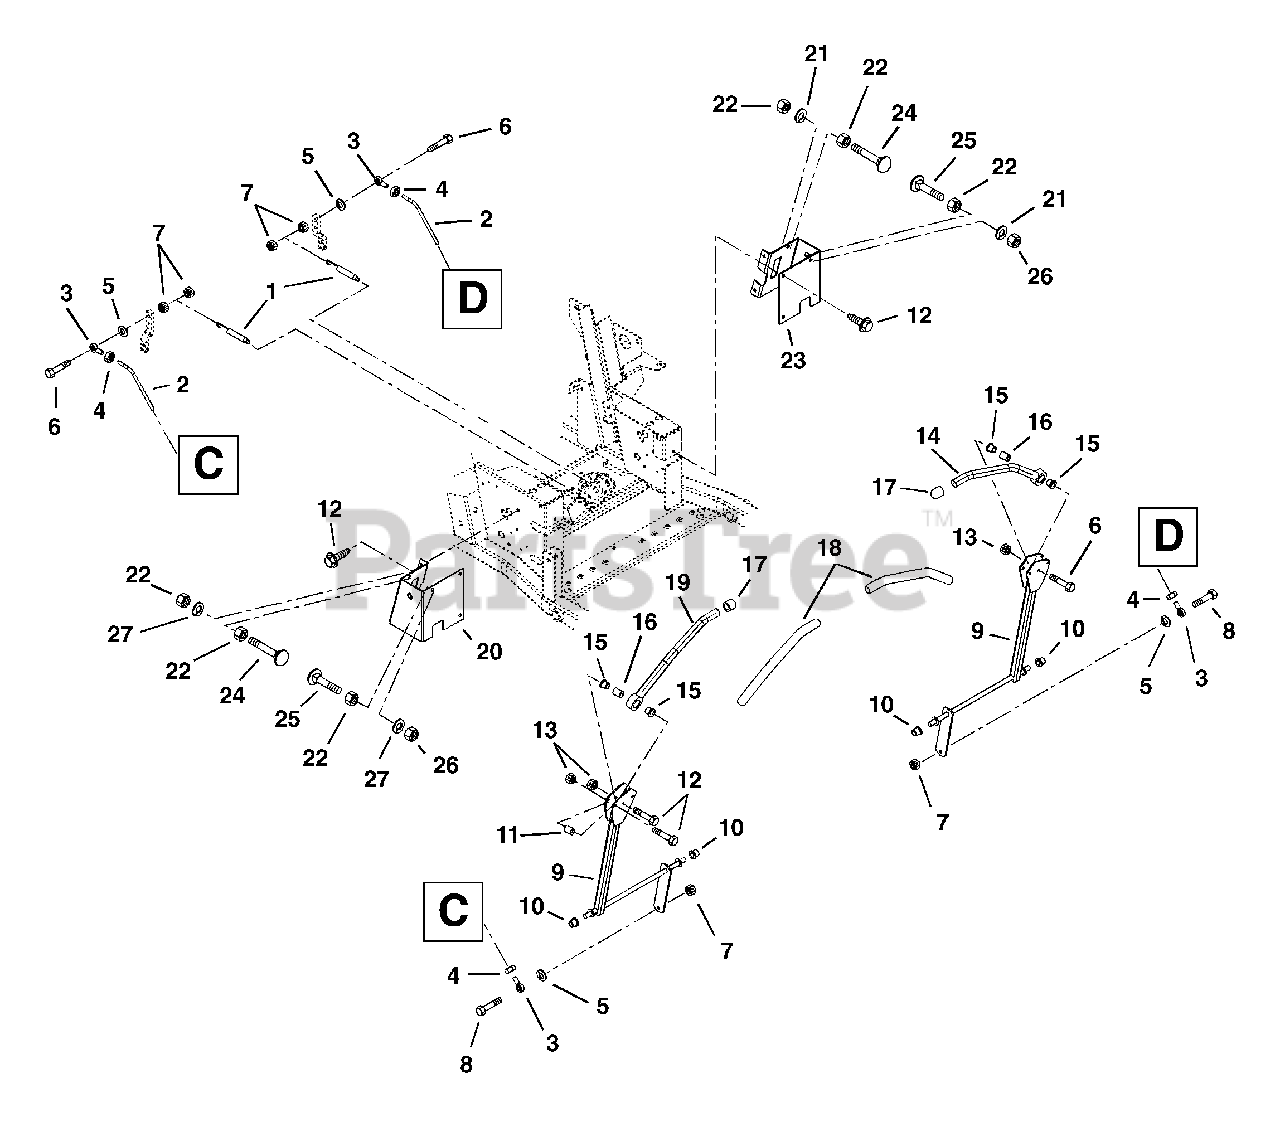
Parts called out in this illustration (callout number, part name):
1	Spring-Tension .062 x .56 x 8.0
2	Rod-Steering Adjustment
3	Rod End 5/16 Right-Hand-Female
4	Nut-Jam .31 - 24
5	Washer-Locking .31 x .078
6	Bolt-Hex .31 - 18 x 1.75 Grade 5
7	Nut-Locking-Center .31 - 18
8	Bolt-Hex .31 - 18 x 1.50 Grade 5
9	Rod-Steering
10	Bushing-Flange .515 x .750 x .745 x 1.00
11	Eccentric
12	Screw-Tapping .38 - 16 x .75 Hex Washer Head
13	Nut-Locking-Center .31 - 18
14	Handle Weldment Left-Hand
15	Bushing-Flange-Nylon .762 x 1.48 x .44
17	End Cap-Steering Lever Tube
18	Grip-Handlebar
19	Handle Weldment Right-Hand
20	Mount-Steering Rod-Right Hand
21	Washer-Locking .38 x .094
22	Nut-Hex .38 - 16
23	Mount-Steering Rod-Left Hand
24	Bolt-Round Head Square Neck .38 - 16 x 2.00
25	Bolt-Round Head Square Neck .38 - 16 x 1.50
